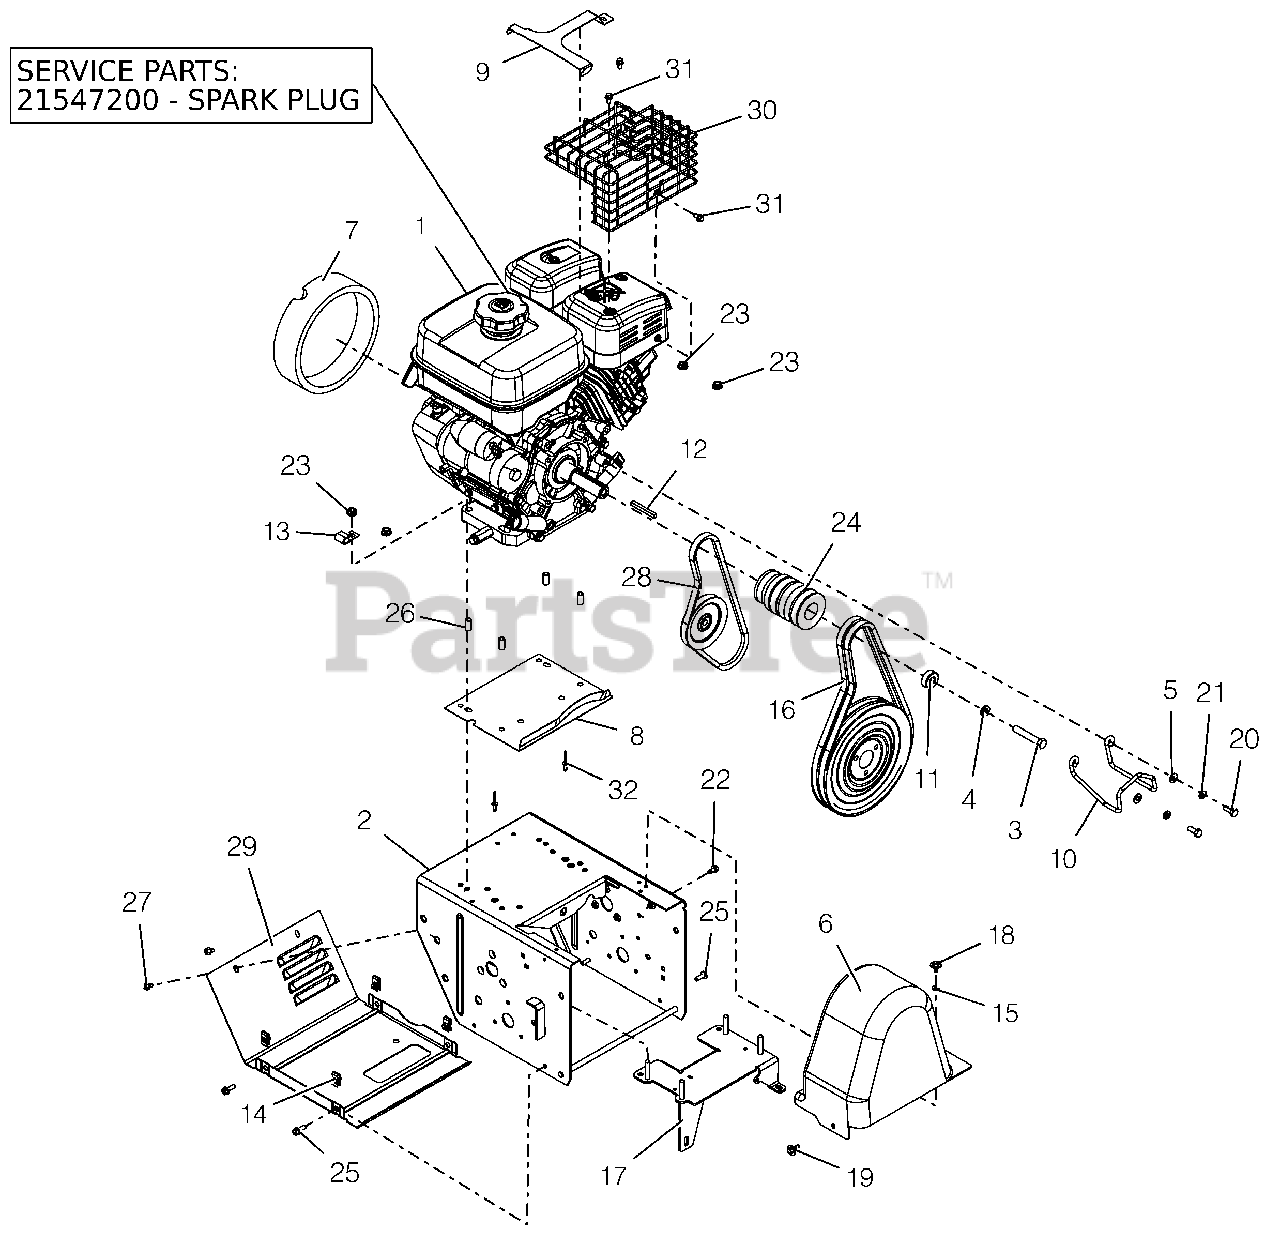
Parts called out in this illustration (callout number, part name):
1	ENGINE,SUBARU EX30 AS 12V
1	PLUG, SPARK SUBARU
2	FRAME, MAIN - PRO (WELDMENT)
3	BLT-HEX .44-20X2.50 GR5 YWZC
4	@WSHR-LK .44X.109 REG YWZC
5	@WSHR-FL-STL.344X.688X.065YWZC
6	COVER, BELT-TALL PRO
7	FOAM COVER, RECOIL-SUBARU
8	BAFFLE, WATER - LARGE BLOCK
9	GUARD, SNOW-SUBARU
10	FINGER, BELT
11	BSHG-SPACER .47X1.25X.50
12	KEY .25X.25X2.25
14	NUT-RTNR .25-20X.56
15	NUT-PUSH .25X.50 O.D.
16	V-BELT, HA-RAW EDGE (SET)
17	BRKT, HYDRO TRANS LG
18	SCR-TAP .25-20X.50 LGHWH TR YZ
19	SCR-TAP .25-20X.5 CAPTIVE
20	BLT-HEX .31-24X.75 YWZC GR5
21	WSHR-LK .312X.097 HVY YWZC
22	SCR-TAP .25-20X.50 HWH TR YWZ
23	@NUT-LK-CTR-FLG .31-18 YZ GR F
24	SHEAVE, COMBO HYDRO BRUSH
25	BLT-HEX .25-20X.75 HWH YZ GR5
26	BSHG-SLV .325X.400X.795
27	SCR-TAP .25-20X.50 HWH TR YWZ
28	V-BELT, 4L-WRAPPED
29	COVER, BOTTOM - VENTILATED
30	MUFFLER GUARD, SUBARU EX27
31	BLT-SERHFWH M6X1.0X12 8.8 CZ
32	RVT-POP .187 YZ
